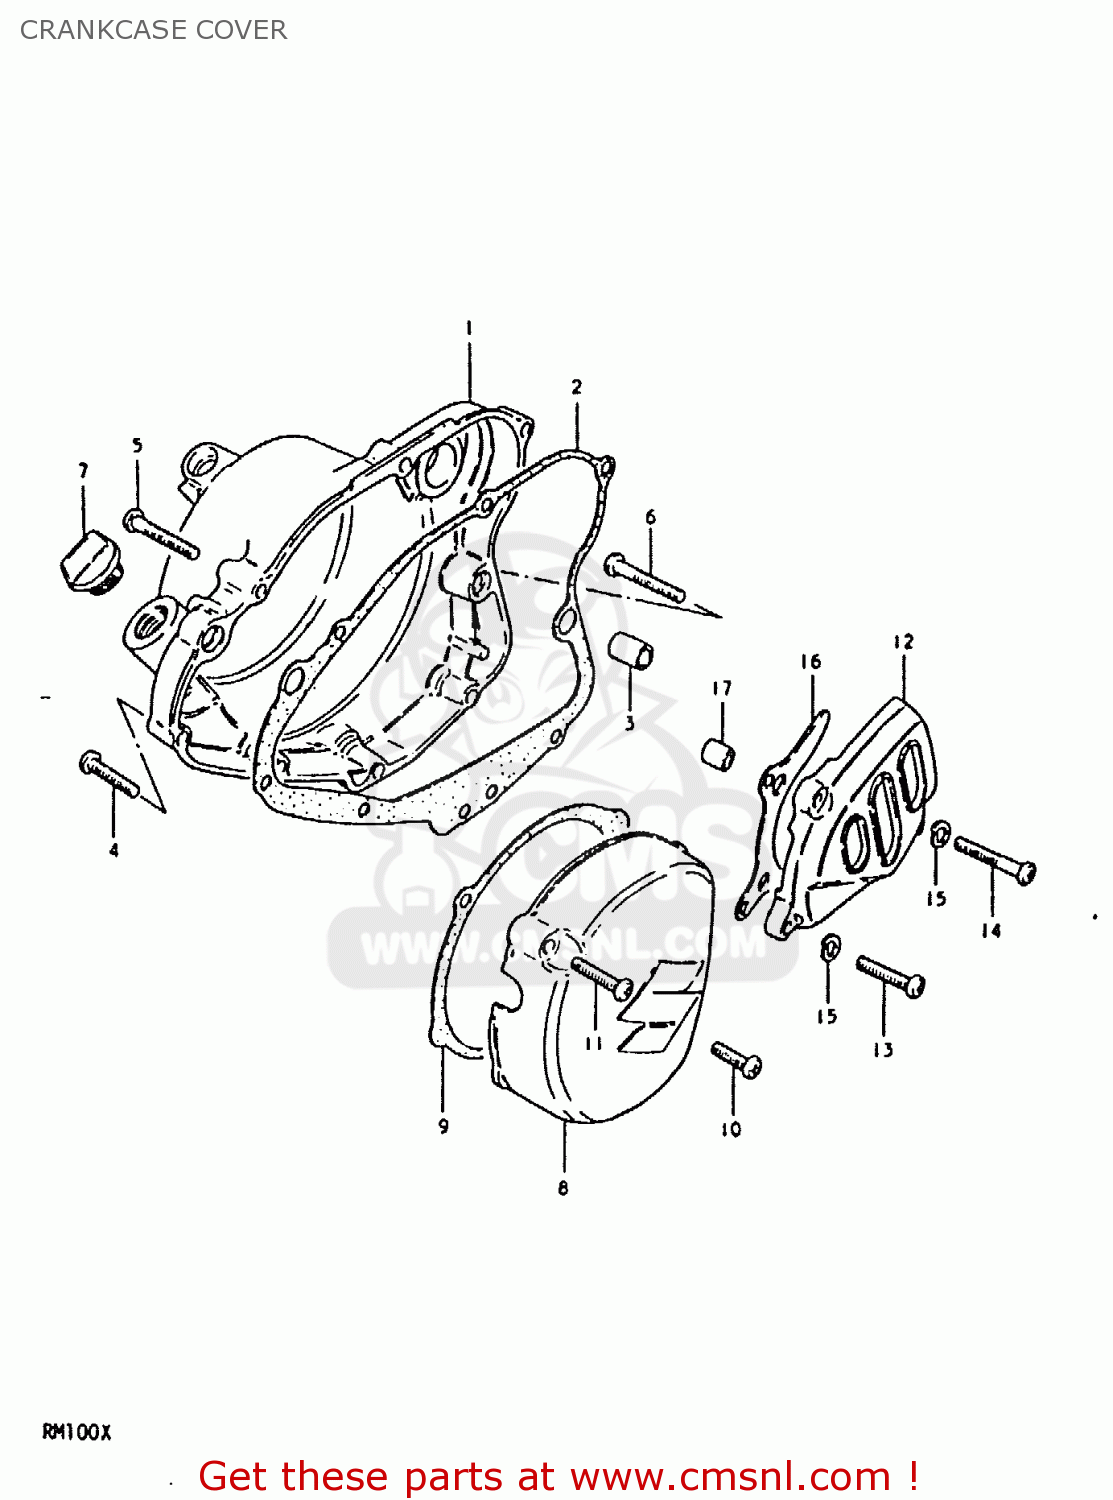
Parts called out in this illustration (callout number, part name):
1	COVER,CLUTCH
2	GASKET,CLUTCH COVER (MCA)
3	PIN
4	SCREW 6X30
5	SCREW
6	SCREW (6X45)
7	PLUG,OIL FILTER
8	COVER
9	GASKET,MAGNETO COVER (MCA)
10	SCREW
11	SCREW 6X30
12	COVER,ENGINE SPROCKET
13	BOLT 6X35
14	SCREW (6X45)
15	LOCK WASHER
16	PLATE,CHAIN FRONT GUIDE
17	SPACER(6.5X10.5X12)
